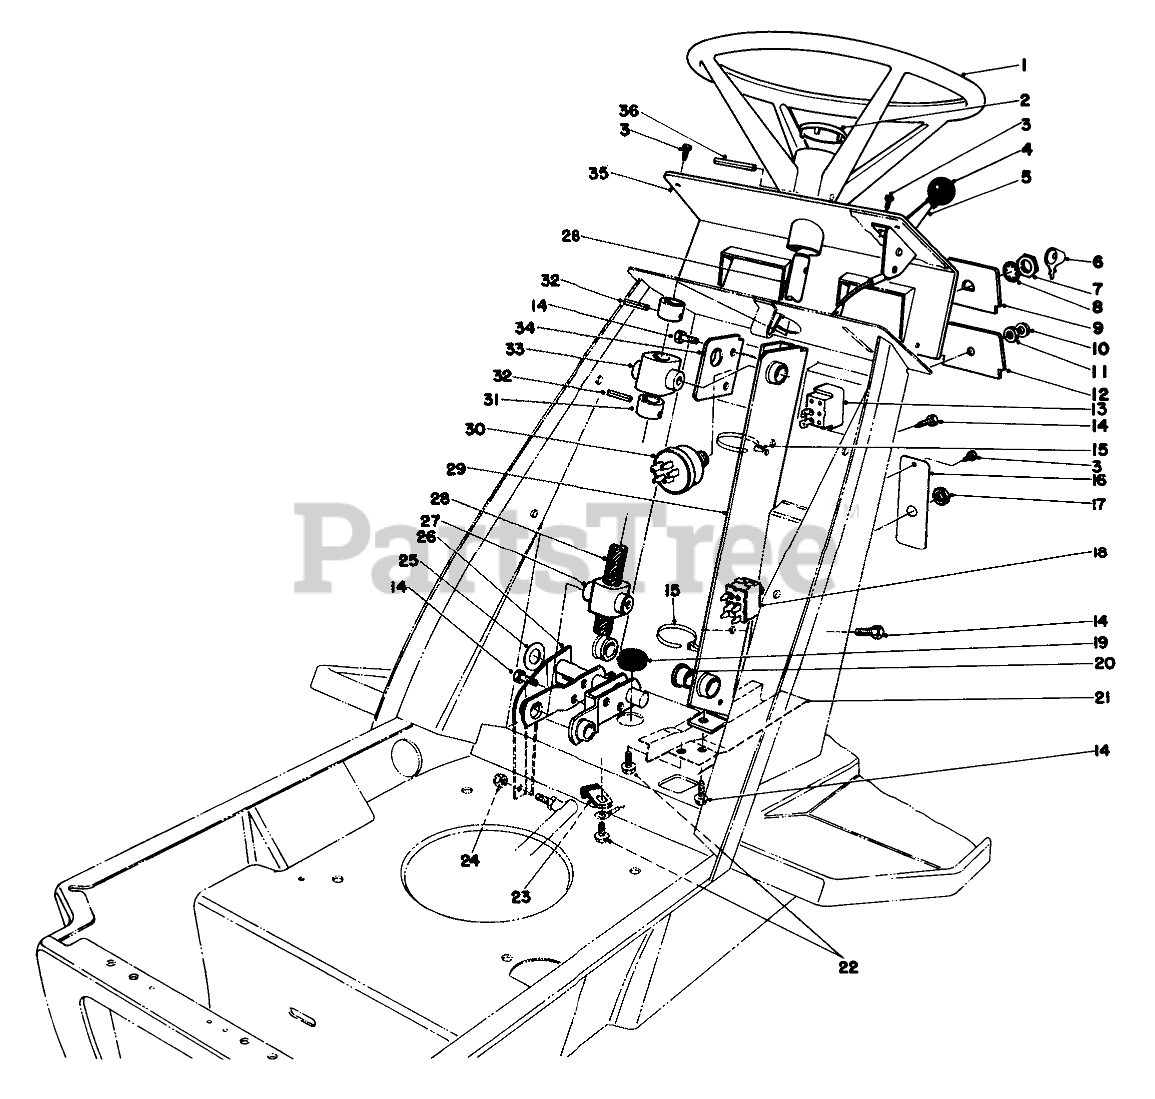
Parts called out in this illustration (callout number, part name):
1	Steering Wheel
2	STRG WHEEL INSERT
3	SCREW-HWHTF
4	KNOB-CONTROL
5	Throttle Control (Incl. Ref. #4)
6	Key
7	NUT-HH
8	WASHER-TOOTH, INTERNAL
9	DASH PANEL INSERT
10	NUT-BULB
11	NUT-LOCK
12	DASH PANEL INSERT
13	Light Switch (Incl. Ref. #10 & 11)
14	SCREW-HWHTF
15	Push Mount Tie (Incl. with Wire Harness)
16	CLUTCH PLT SWITCH
17	NUT
18	Switch-Clutch (Incl. Ref. #17)
19	GROMMET
20	BEARING-FLANGE
21	WIRE HARNESS SHLD B
22	SCREW-HWH
23	CLIP-FUEL LINE
24	NUT-HEX
25	WASHER
26	STEERING LINK WA BO
27	FOLLOWER STEER SHAFT
28	STEERING SHAFT
29	STRG BRKT B
30	Ignition Switch (Incl. Ref. #6-8)
31	STRG SHAFT COLLAR
32	PIN-SPRING
33	BRG STEERING SHAFT
34	STRG BRG SUPPORT
35	DASH PANEL
36	PIN-ROLL
